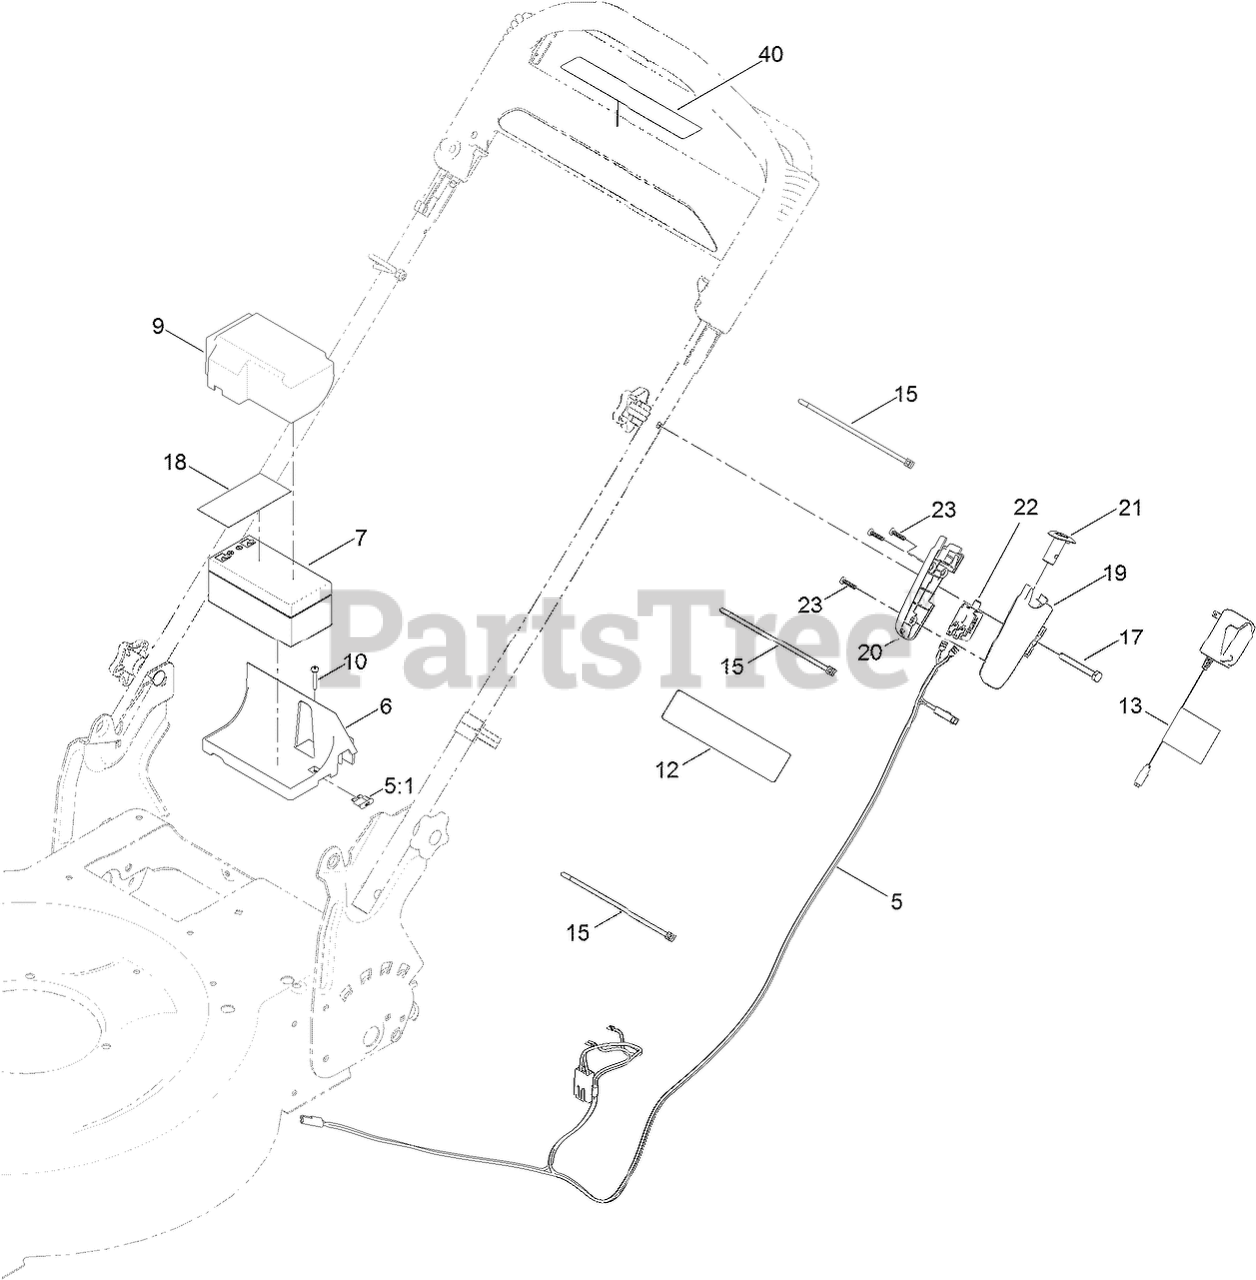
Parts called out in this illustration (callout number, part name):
5	HARNESS-WIRE
5:1	FUSE-40 AMP
6	TRAY-BATTERY
7	BATTERY-WET
9	COVER-BATTERY
10	SCREW-PPH, PLASTITE
12	DECAL-WARNING
13	CHARGER-BATTERY
15	TIE-CABLE
17	SCREW-HH
18	DECAL-TERMINAL, BATTERY
19	HOUSING-SWITCH, LH
20	HOUSING-SWITCH, RH
21	BUTTON-SWITCH
22	SWITCH-PUSH BUTTON
23	SCREW-PPH
40	DECAL-BUTTON, PUSH
